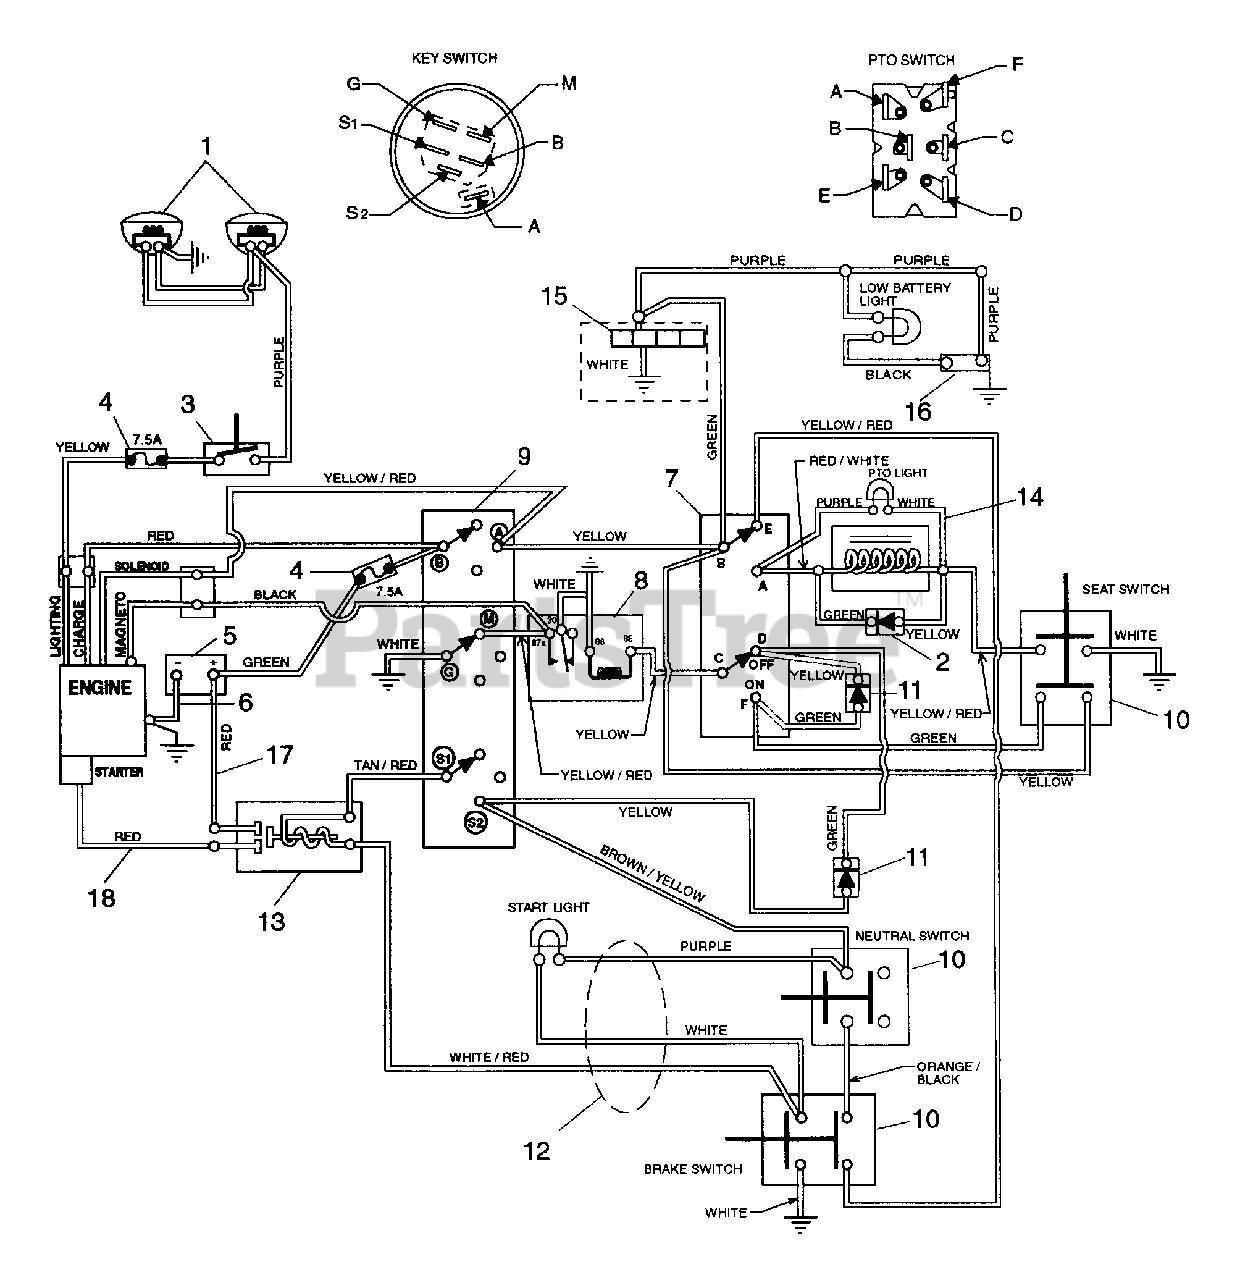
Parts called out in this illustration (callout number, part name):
1	HEADLIGHT- L.H.
1	HEADLIGHT- R.H.
2	DIODE & HOUSING
3	LIGHT SWITCH
4	7.5 Amp Fuse
5	BATTERY W/TUBE
6	GROUND CABLE .31X22.00X.31
7	SWITCH ASSEMBLY- PTO
8	RELAY
9	KEY SWITCH
10	SWITCH- DOUBLE POLE N.O./N.O.
11	MOLDED DIODE PLUG 1 AMP
12	WIRE HARNESS- YT140H
13	SOLENOID
14	ELECTRIC CLUTCH/BRAKE(1.8AMP)
15	HOURMETER
16	VOLTAGE SENSOR
17	START CABLE 22"
18	STARTER CABLE 6.75"
